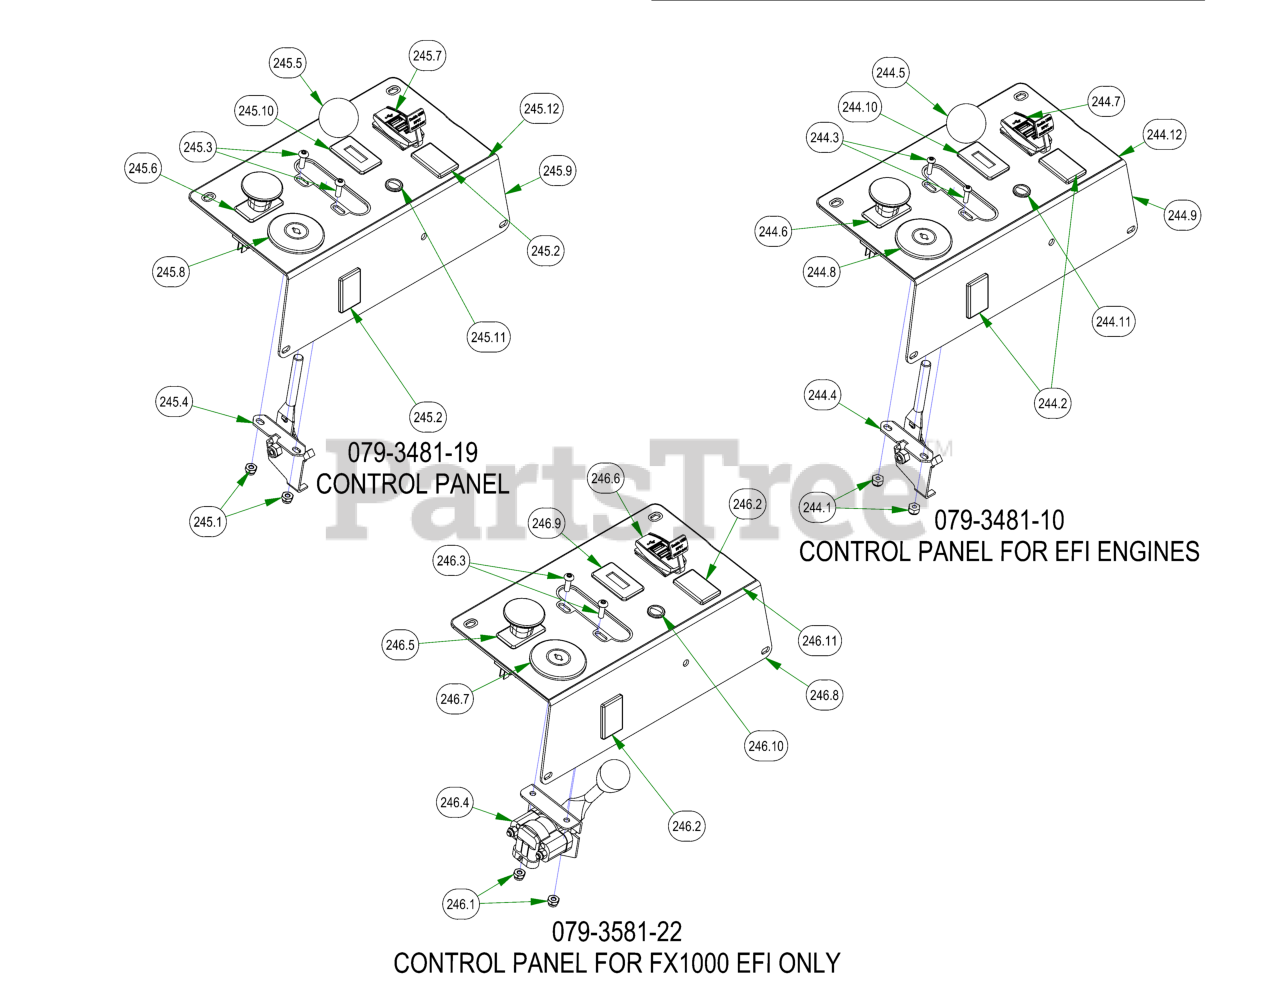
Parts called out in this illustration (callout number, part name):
244	Rebel/Rogue EFI Control Panel Assy
244.1	10-24 Nylon Insert Locknut Zinc Orange Nylon
244.2	Light Plug
244.3	10-24 X 5/8 BS Button Head Bolt
244.4	Universal Throttle Head - 2012
244.5	Throttle Knob
244.6	PTO Switch
244.8	Ignition Switch
244.9	2022 Rebel Control Panel
244.10	Tachometer
244.12	2022 Rebel/Rogue Control Panel Decal
245	Rebel/Rogue Control Panel Assy
245.1	10-24 NYLON INSERT LOCKNUT ZINC
245.2	Light Plug
245.3	10-24 X 5/8 BUTTON SOCKET CAP SCREW 18-8 STAINLESS STEEL
245.4	Universal Throttle Head - 2012
245.5	Throttle Knob
245.6	PTO Switch
245.8	Ignition Switch
245.9	2022 Rebel Control Panel
245.10	Tachometer
245.12	2022 Rebel/Rogue Control Panel Decal
246	Rebel/Rogue Control Panel Assy-Drive by Wire
246.1	10-24 NYLON INSERT LOCKNUT ZINC
246.2	Light Plug
246.3	10-24 X 5/8 BUTTON SOCKET CAP SCREW 18-8 STAINLESS STEEL
246.4	Kawasaki \ Kohler Drive By Wire
246.5	PTO Switch
246.7	Ignition Switch
246.8	2022 Rebel Control Panel
246.9	Tachometer
246.11	2022 Rebel/Rogue Control Panel Decal
